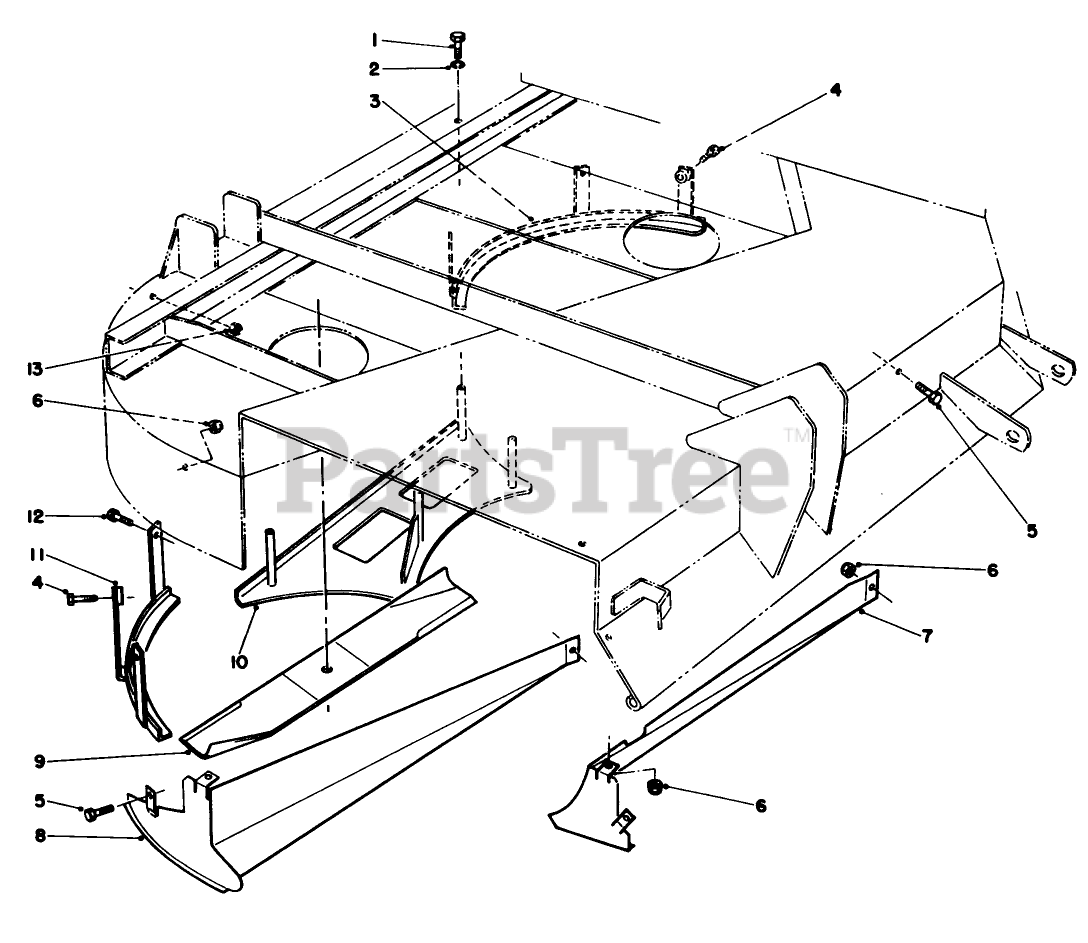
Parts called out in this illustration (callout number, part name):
1	SCREW-HH
2	WASHER-LOCK
3	Shelf-Bottom, Left
4	SCREW-HH
5	SCREW-HH
6	NUT-LOCK, NI
7	Deflector-Front
8	Deflector-Rear
9	BLADE-HIGH SAIL
10	Shelf-Rear
11	Shelf-Right
12	SCREW-HH
13	NUT-LOCK, NI
